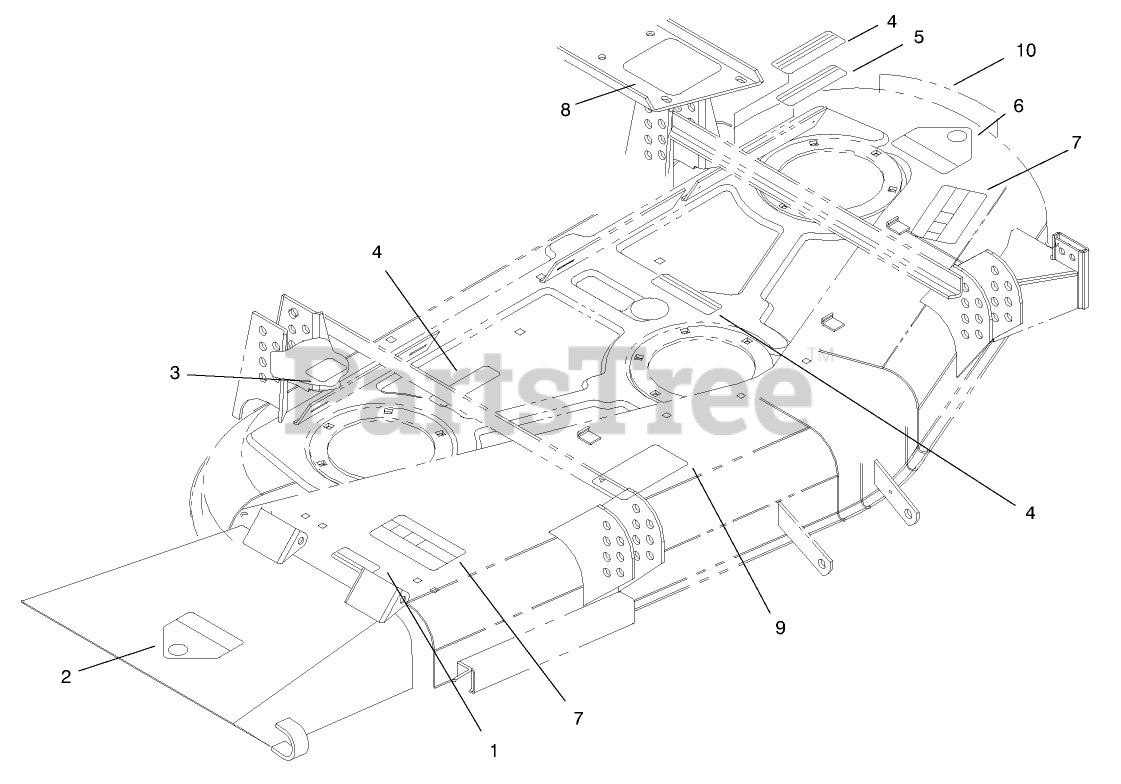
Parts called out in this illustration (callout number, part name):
1	DECAL-DANGER
2	DECAL-DANGER
4	DECAL-DANGER
5	DECAL-TORQUE
6	DECAL-DANGER
7	DECAL-DANGER, THROWN OBJECT
8	DECAL
9	DECAL-WARNING
10	DECAL-RECYCLER
